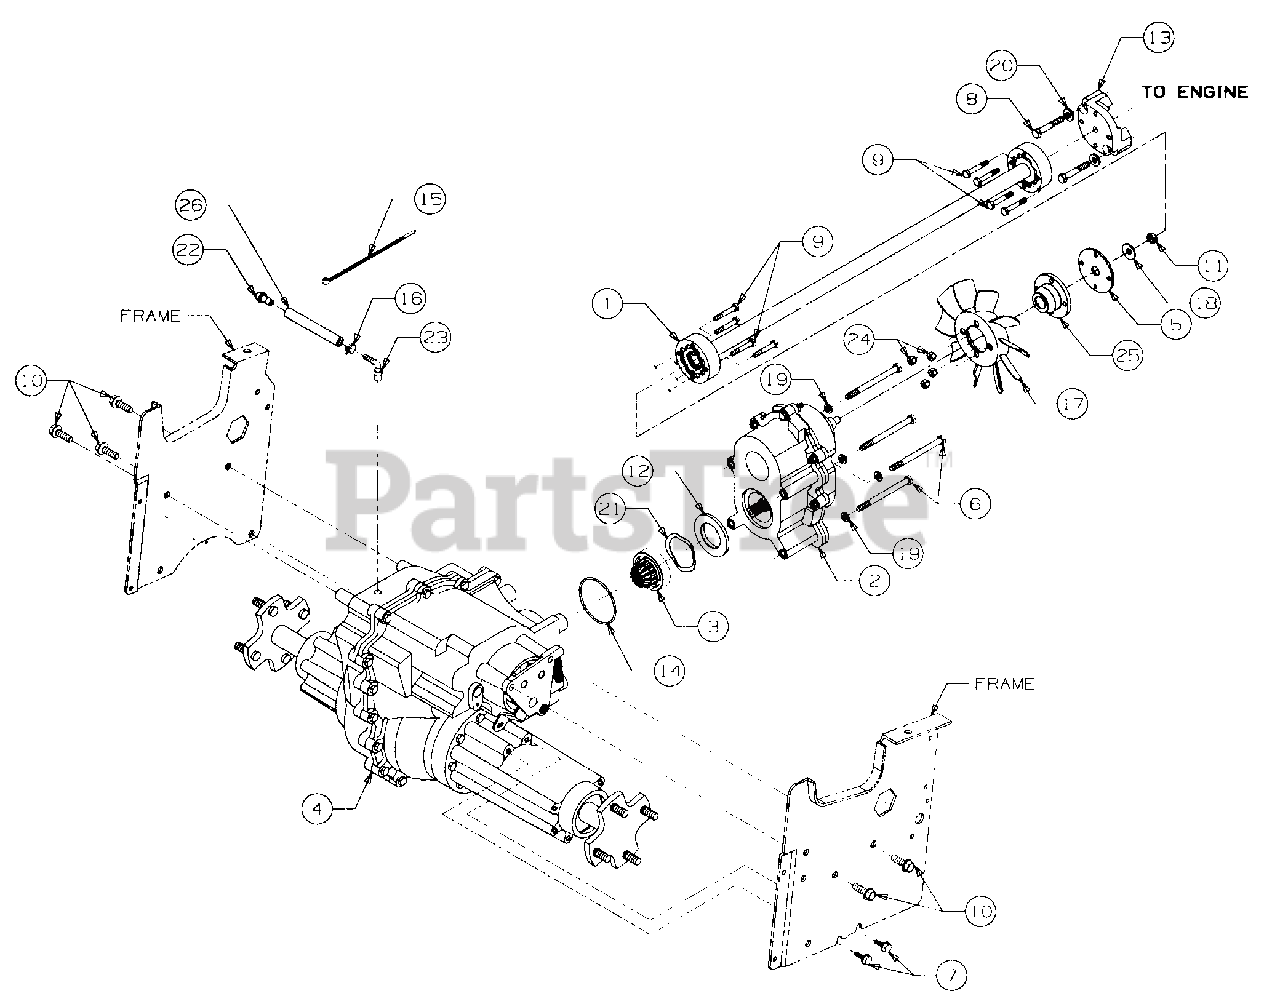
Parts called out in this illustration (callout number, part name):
1	Shaft Assy, Drive, 27.87 Lg
2	Clutch Assy
3	Pinion Assy, Input
4	Transmission Assy, 6-Speed
5	Plate, Drive Shaft Spacer
6	Screw, Hex Cap, 5/16-18 x 4.0 Lg GR5
7	Screw, Hex Wash Sf-Tapp 5/16-18 x .75 Lg
8	Bolt, Hex Patch, M8-1.25 x 50 mm
9	Bolt, Hex Patch, 1/4-20 x 1.62 Lg GR5
10	Screw, Hex Wash Tapp 3/8-16 x 1.25 Lg
11	Nut, Hex Center Lock Jam 3/8-24
12	Plate, Clutch Output Shim
13	Adapter, Drive Shaft
14	O-Ring, 2.75 x .103
15	Tie, Self-Clinch Cable
16	Clamp, Hose
17	Fan, 10 Blade Cooling
18	Washer, Bell, .380 x .88 x .062 Thk
19	Washer, Lock, 5/16
20	Washer, Flat, .312 x .750 x .119 Thk
21	Washer, Spring Wave, 1.96 x 2.44 x .06 Thk
23	Fitting, Elbow
24	Nut, Fan, 1/4-20
25	Adapter, Clutch
26	Line, Fuel 7 in. Lg.
